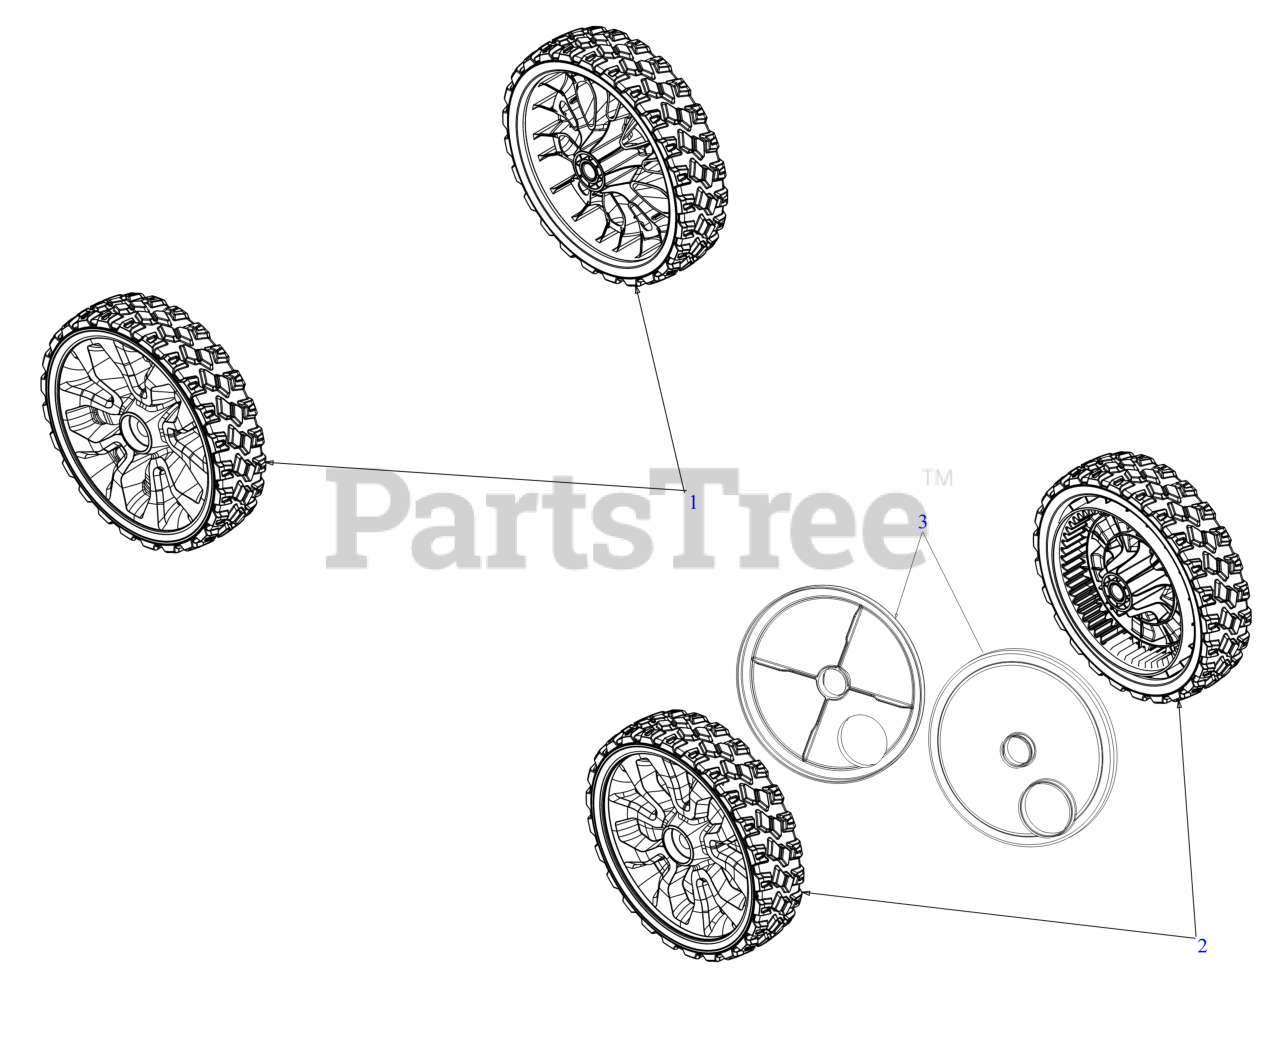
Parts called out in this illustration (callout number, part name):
1	IDLE WHEEL (8x2) (DeWALT GRAY)
2	DRIVE WHEEL (8x2) (DeWALT GRAY)
3	WHEEL DUST COVER
